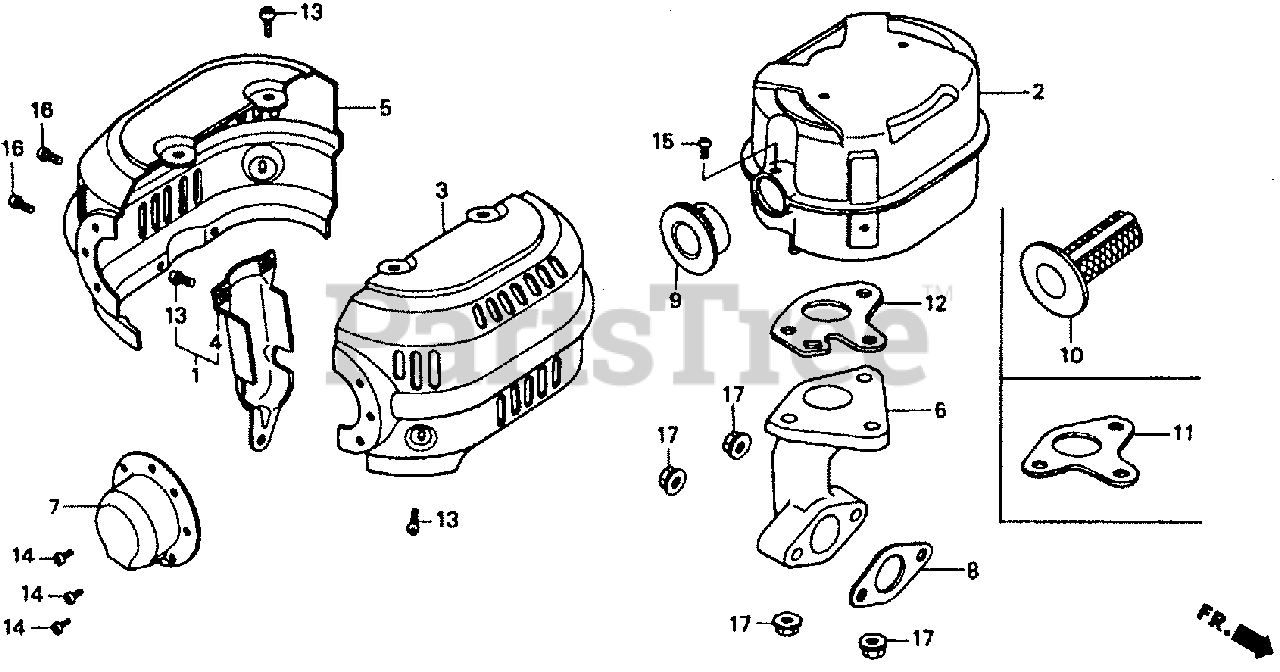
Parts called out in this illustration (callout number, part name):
1	PROTECTOR, EX. PIPE
2	MUFFLER
3	PROTECTOR, R. MUFFLER (Honda Code 4049912). (ALUMINIZED)
4	PROTECTOR, EX. PIPE
5	PROTECTOR, L. MUFFLER (Honda Code 4049946). (ALUMINIZED)
6	PIPE, EX.
7	CAP, MUFFLER
8	GASKET, EX. PIPE
8	GASKET, EX. PIPE (WACKER)
11	GASKET, MUFFLER
13	SCREW, TAPPING (5X8)
14	SCREW, TAPPING (4X6)
16	SCREW, PAN (5X8)
17	NUT, FLANGE (8MM)
